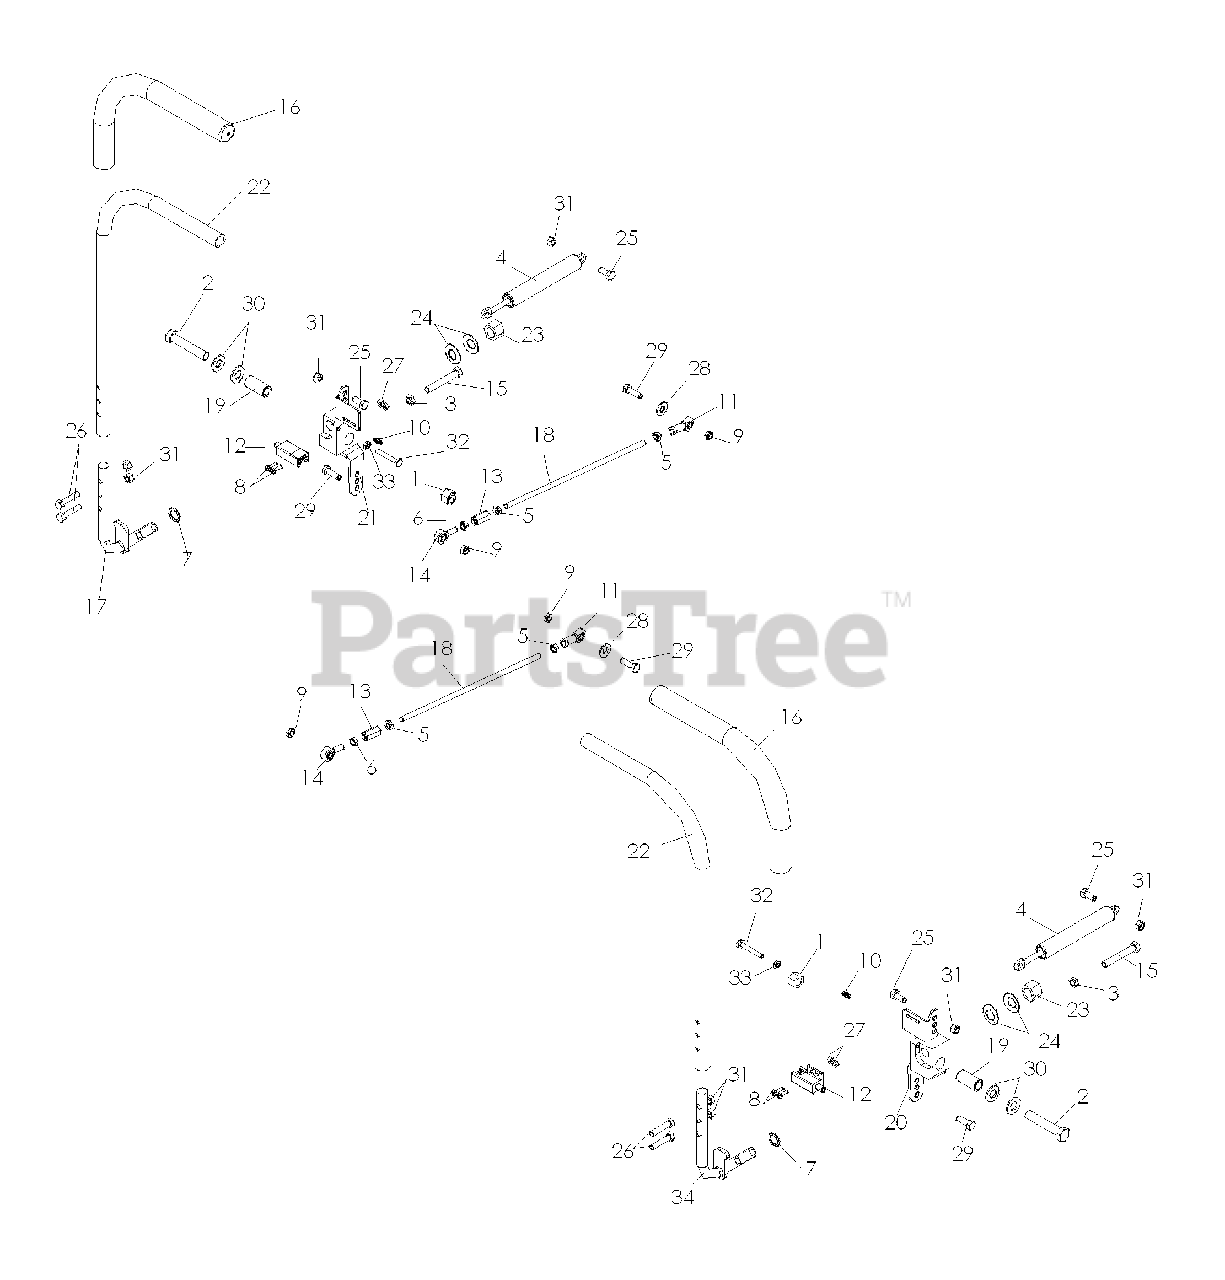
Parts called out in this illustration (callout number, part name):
1	NUT 1/2-13 HEX NYLOC ZD
2	HCS 1/2C X 2 3/4
3	NUT 3/8-16 HEX JAM
4	DAMPENER, DUAL ACTION
5	NUT 5/16-24 UNF HEX JAM
6	NUT 5/16F LEFTHAND
7	SUPPORT SPRKT SPACER
8	SCREW #10-24 X 5/8
9	5/16-18 THIN PROF NY
10	ZERK, 3/16, DRIVE IN
11	RH ROD END
12	SWITCH, INTERLOCK
13	ROD END COUPLER
14	ROD.END.LH
15	HHB 3/8-16X2-1/2 GR5ATHD
17	LOWER LVR WLDT.(PLATED)
19	BUSHING
20	PIVOT LH (PLATED)
21	PIVOT RH (PLATED)
22	UPPER LEVER, BLK
23	NUT 5/8-11 NYLOC
24	WASH 5/8 BEVELED DISC SPRING
25	HCS 5/16C X 3/4
26	CAPSCREW 5/16 X 1/1/2 HEX HEAD
27	NUT 10-24 NYLOC
28	FLAT WASHER 5/16 SAE
29	HCS 5/16C X 1
30	WASHER 1/2" FLAT
31	NUT 5/16 NYLOC
32	BOLT 1/4C X 1 3/4
33	NUT 1/4-20 JAM
34	LOWER LEVER WLDT LH PLTD
